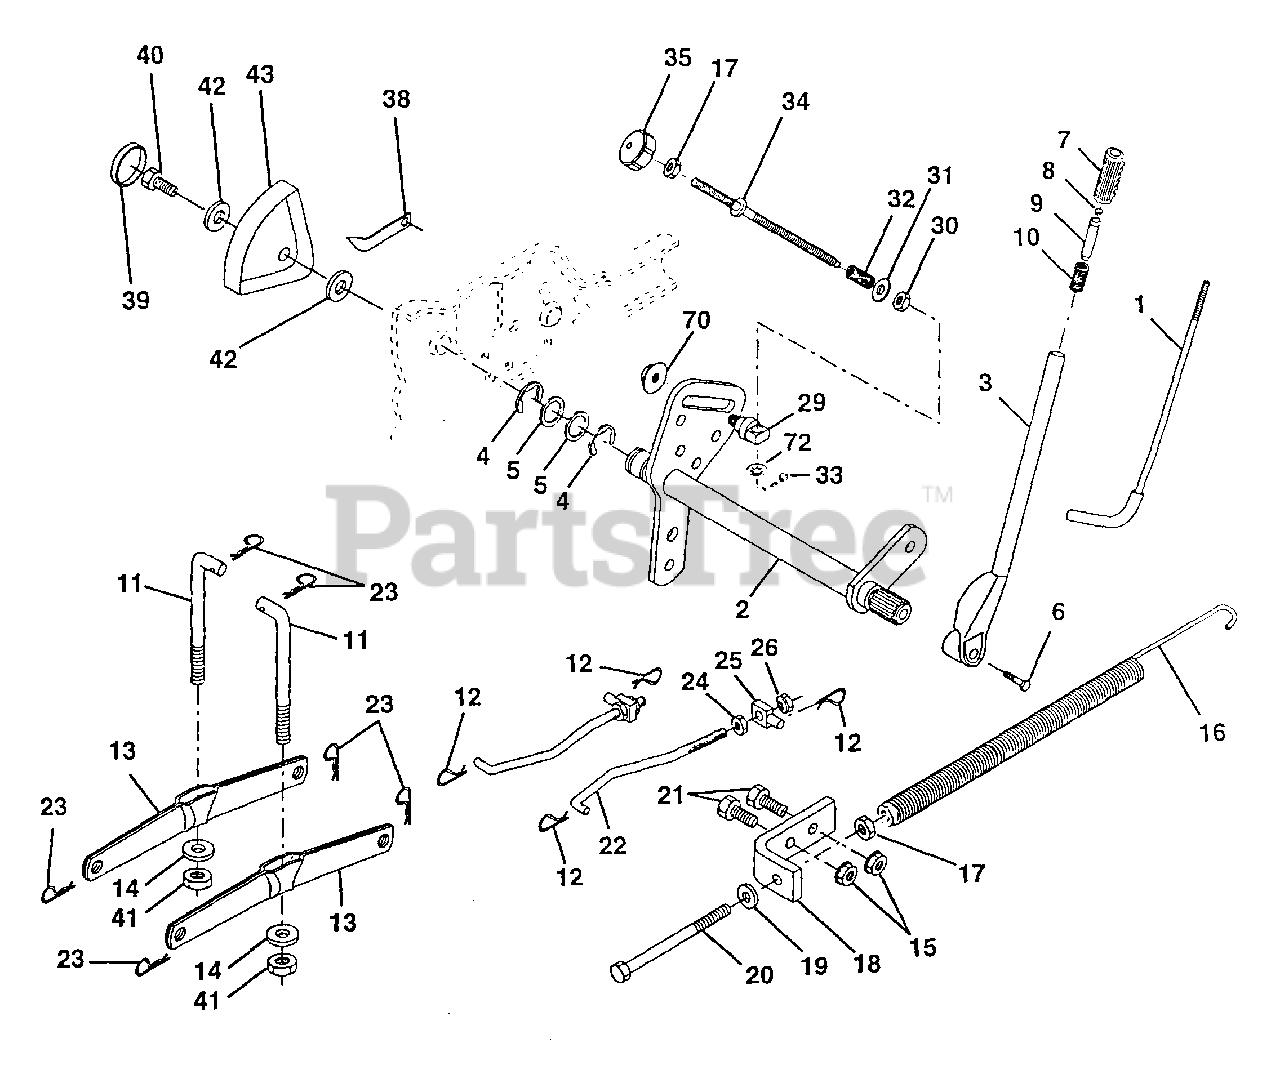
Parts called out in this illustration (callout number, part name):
1	Rod Asm., Lever
2	Shaft Asm., Lift Vgt (AYP part number)
3	Lever Asm., Lift Rh (AYP part number)
4	E-Ring Truarc #5133-87
5	Washer 29/32 x 1-1/4 x 16 Ga
6	Bolt, Fin Hex 3/8-16 x 1-1/2
7	Grip, Handle Fluted
8	Button, Plunger (AYP part number)
9	Plunger, Lever Lift (AYP part number)
10	Spring 2-1/8"
11	Link Lift (AYP part number)
12	Retainer, Spring
13	Arm, Suspension Vgt
14	Bearing (AYP part number)
15	Nut, Crownlock 3/8-16
16	Spring Asm., Assist Lift
17	Nut, Hex Jam 3/8-16 Unc
18	Bracket, Spring Assist
19	Washer 13/32 x 13/16 x 16 Ga.
20	Bolt, Adjust Spring Assist
21	Bolt, Fin Hex 3/8-16 x 1
22	Link, Front
23	Retainer, Spring (AYP part number)
24	Nut, Jam Hex 1/2-13 Unc
25	Trunnion (AYP part number)
26	Nut, Lock W/Wsh 1/2-13 Unc (AYP part number)
29	Trunnion Infin Height
30	Nut, Special
31	Washer 13/32 x 5/8 x 16 Ga
32	Spring, Compression Inf Hgt
33	Pin, Cotter 3/32 x 1/2 (AYP part number)
34	Rod, Adj Lift
35	Knob, Inf 3/8-16 Unc
36	Screw, Thdrol 3/8-16 x 3/4
38	Pointer Height Indicator
39	Plug, Hole
40	Screw, Thdrol 5/16-18 x 3/4 TYT
41	Nut, Crownlock 3/8-24 (AYP part number)
42	Washer 11/32 x 1-1/2 x 10 Ga
43	Scale, Indicator Height
70	Nut Hexflange Lock
72	Nut Push Phos & Oil
